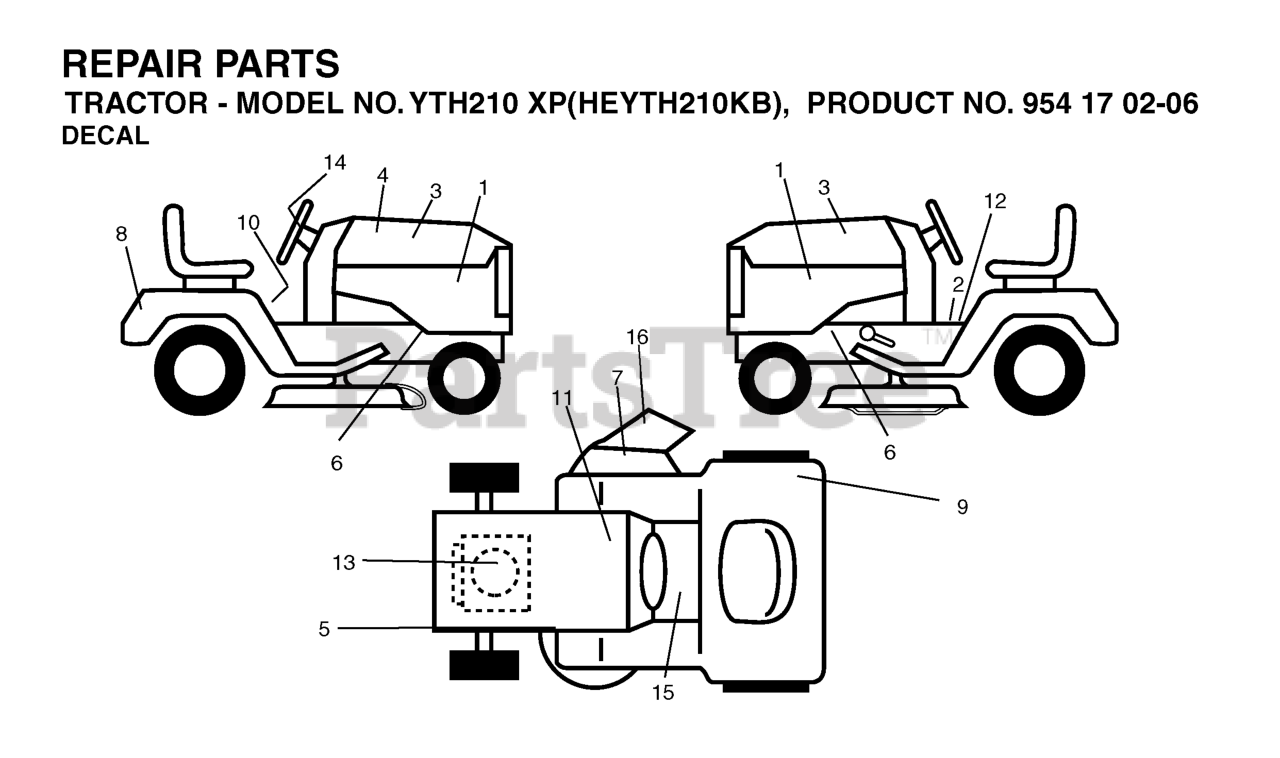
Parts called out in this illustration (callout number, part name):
1	DECAL.HOOD.HUSQVARNA.INTERNATI
2	DECAL PARK BRAKE
5	DECAL V BELT SCHEMATIC
7	DECAL.INTERNATIONL.CUTFINGER
9	Decal, Fender 100 DB/CE
10	DECAL READ OWNER'S MAN SYMS
11	DECAL BTRY SYMBOLS
12	DECAL
14	DECAL.STEERING.HUSQ.BLUE
15	DECAL
16	DECAL DECK "B" 42"
